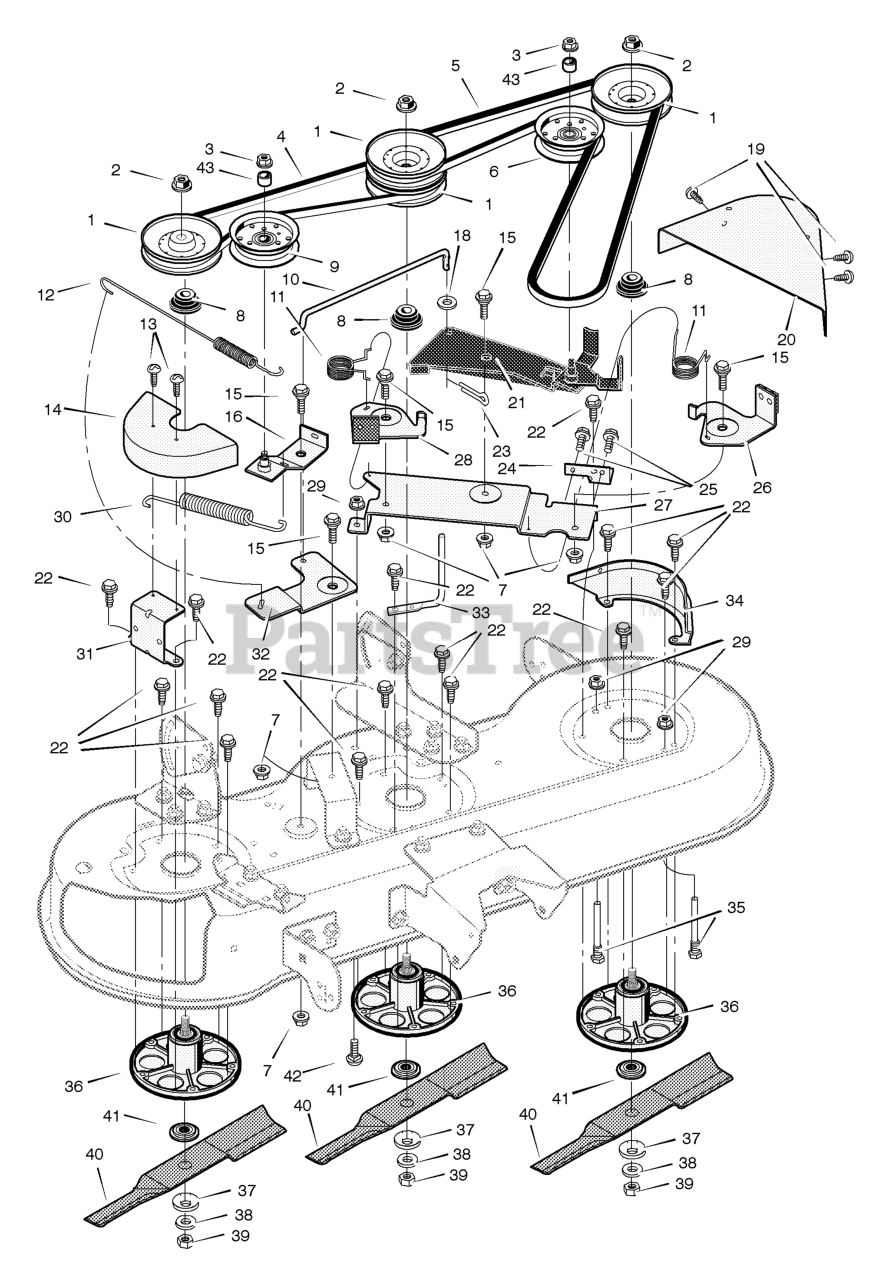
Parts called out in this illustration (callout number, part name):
1	Pulley
3	Nut
4	Belt, Secondary
5	Belt, Primary
6	Pulley, Idler
7	Locknut
8	Spacer, Pulley
9	Pulley, Idler
10	Link, Bell Crank
13	Screw
14	Cover, Right Pulley
15	Bolt, Shoulder
16	Arm Assembly, Idler
18	Washer
20	Cover, Left Pulley
21	Arm Assembly, Idler
22	Bolt
23	Pin, Cotter
24	Bracket, Brake Plate
26	Brake Assembly, Left
27	Plate, Brake Arm
28	Brake Assembly, Center
29	Nut, Flange
31	Bracket, Cover
32	Bell Crank
33	Guide, Belt
34	Bracket, Pulley Cover
35	Guide, Belt
36	Ass'y, Jackshaft Housing
39	Nut, Blade
41	Adapter, Blade
42	Bolt, Carriage
